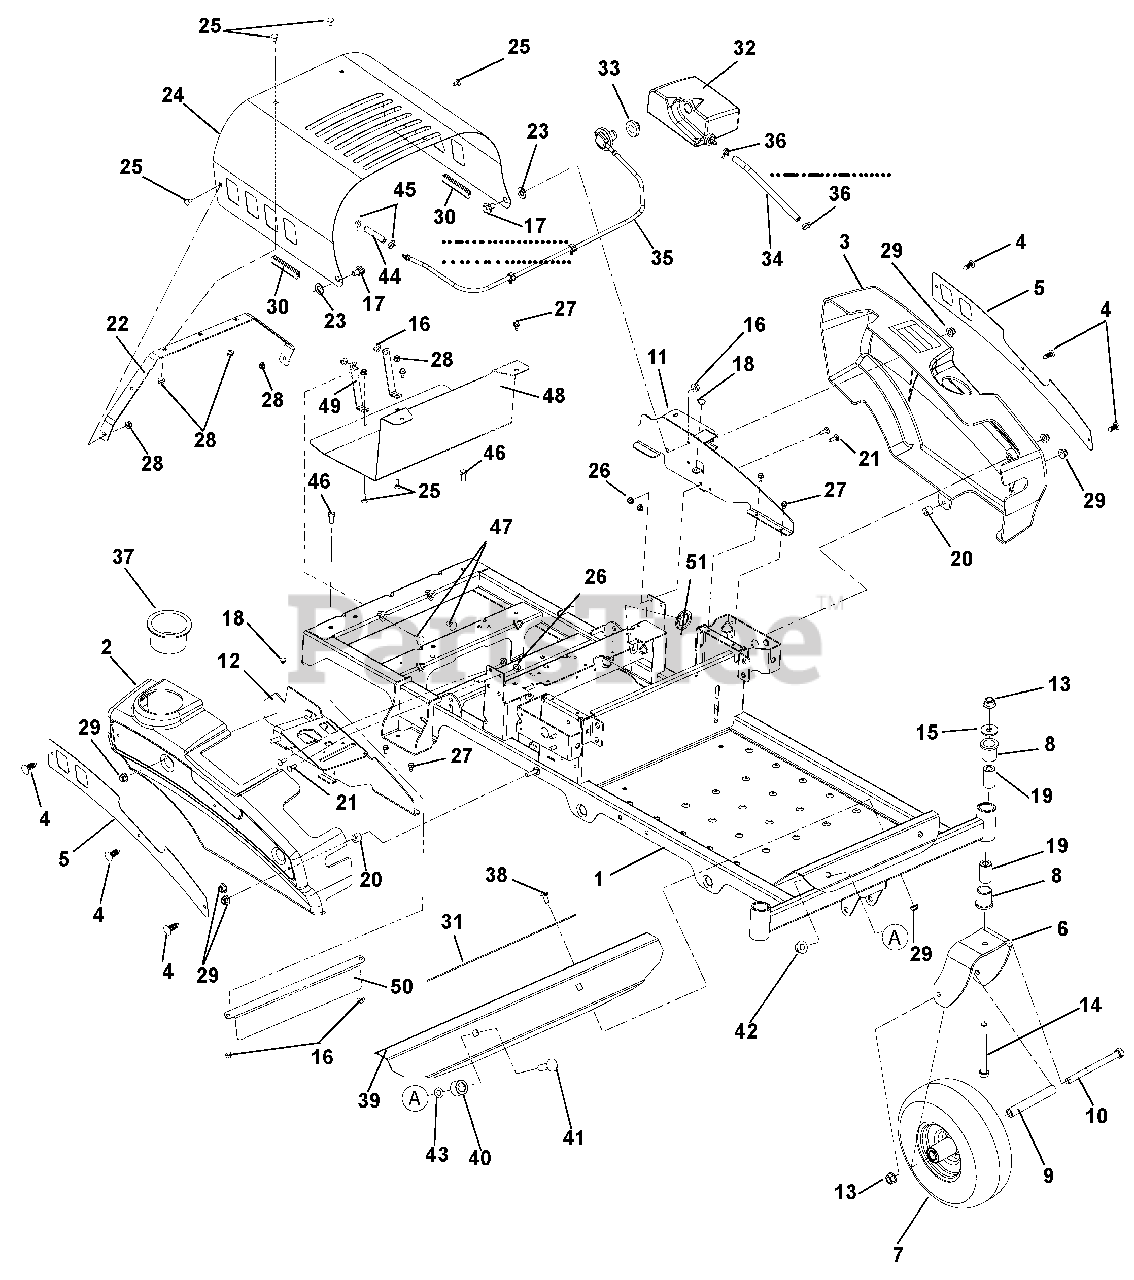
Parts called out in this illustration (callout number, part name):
1	KIT, ZOOM/ZT FRAME W/ DECALS
2	FENDER, RH
3	FENDER, LH
4	RIVET, .25 NYLON PANEL
5	PLATE, FENDER
6	WMT, CASTER FORK
7	TIRE/WHEEL ASSY, 11X4-5
8	BSHG-FLG 1.00X1.25X1.50X1.50
9	SPACER, ROLLED WHEEL
10	@BLT-HEX .50-13X6.50 GR5 YWZC
11	WLDMT, LH FENDER MOUNT
12	WLDMT, RH FENDER MOUNT
13	@NUT-LK-TOP-FLG .50-13 YWZC
14	@BLT-HEX .50-13X5.00 GR5 YWZC
15	WSHR-FL-STL.511X1.441X.125 YWZ
16	@NUT-LK-TOP-FLG .38-16 YWZC
17	BOLT-SHLDR .375-16X.150
18	BUMPER GROMMET
19	SPACER, CASTER .50X1.00X1.84
20	BSHG-SLV .391X.688X.52 PM
21	@BLT-RDHDSQNK .25-20X.75 G5YZ
22	BRACE, HOOD
23	WSHR-FL-NYL .518X1.000X.080
24	HOOD, ZOOM
25	@BLT-RDHDSQNK .25-20X.50 G5YZ
26	@NUT-LK-NYL-FLG .25-20 YWZC
27	SCR-TAP .25-20X.50 HWH TR YWZ
28	@NUT-LK-TOP-FLG .25-20 YWZC
29	@NUT-LK-NYL-FLG .31-18 YWZC
30	EDGING, CLUTCH PADDLE - 2.00"
31	GRIP, ADHESIVE (1" X 16" BLK)
32	EXPANSION TANK SUB ASSY
33	GROMMET, REMOTE VENT NITRILE
34	HOSE, .25 LOW-PERM BULK GAS
35	ASM, FUEL VENT - ZOOM/ZT
36	CLAMP, FUEL LINE
37	CUPHOLDER, SNAP-IN 3.75OD
38	BLT-RDHDSQNK .50-13X7.00
39	FOOTREST
40	TUBE, UPPER CONTROL PIVOT
41	@BLT-RDHDSQNK .50-13X1.75 G5YZ
42	@NUT-LK-NYL-FLG .50-13 YWZC
43	NUT-PUSH, .50
44	HOSE, .188 LOW-PERM BULK GAS
45	CLAMP-HOSE, SPRING .188
46	PLATE, BBZ HITCH KIT PLATE
47	@BLT-HEX .38-16X1.00 GR5 YWZC
48	@BLT-RDHDSQNK .38-16X1.00 G5YZ
49	GUARD, HEAT SHIELD (ZOOM/ZT)
50	STRAP, HEAT SHIELD (ZOOM/ZT)
51	GUARD, HOT SURFACE (ZOOM/ZT)
52	GROMMET 1.0ID X 1.38 OD
